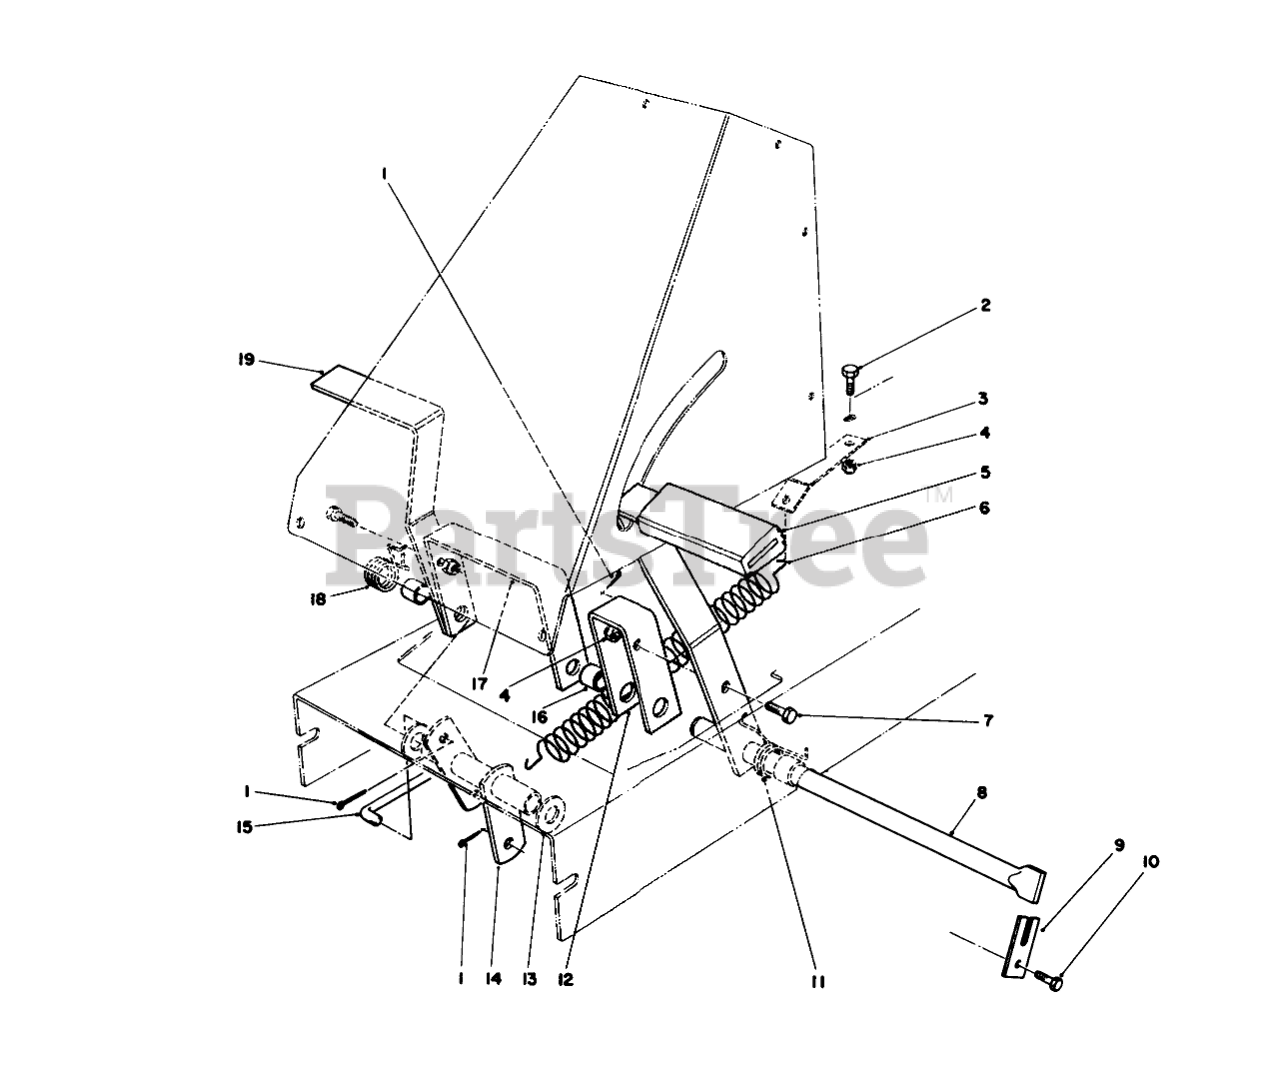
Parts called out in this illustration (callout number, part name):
1	PIN-COTTER
2	SCREW-HH
3	BRKT-SPRING RET
4	NUT-LOCK, NI
5	PAD-PEDAL
6	SPRING-EXTENSION
7	SCREW-HH
8	SHAFT-PEDAL PIVOT
9	RETAINER-SHAFT
10	SCREW-HH
11	SPRING-TORS CLUTCH
12	Bracket-Clutch Pedal
13	WASHER-FLAT
14	Pivot Tube
15	ROD-ENGAGE
16	SPACER-PEDAL
17	Bracket-Brake Pedal
18	SPRING-TORS BRAKE
19	Pedal
